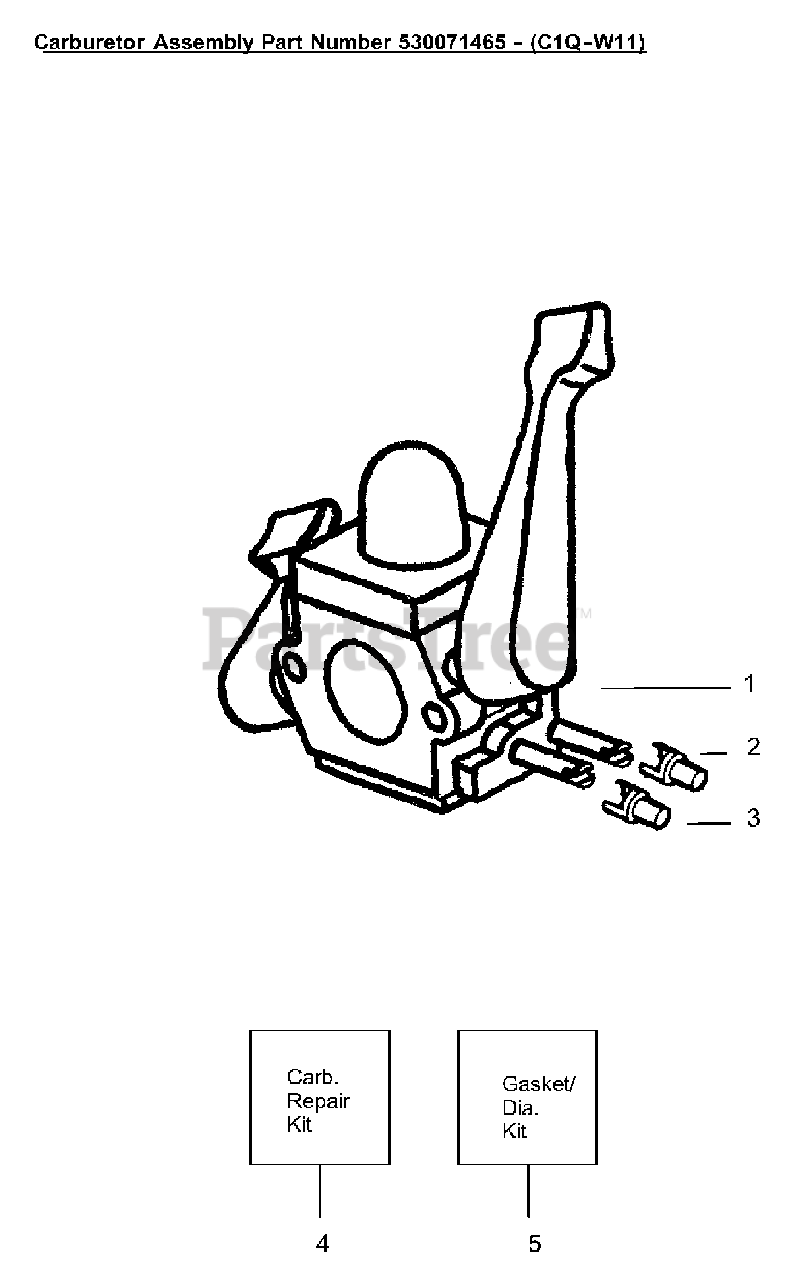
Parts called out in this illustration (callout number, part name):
1	Assy-Carb. Zama (C1Q-W11)
2	Cap-Limiter (high) brown
3	Cap-Limiter (low) tan
4	Kit-Carb. Repair
5	Kit-Dia. (GND-34)
